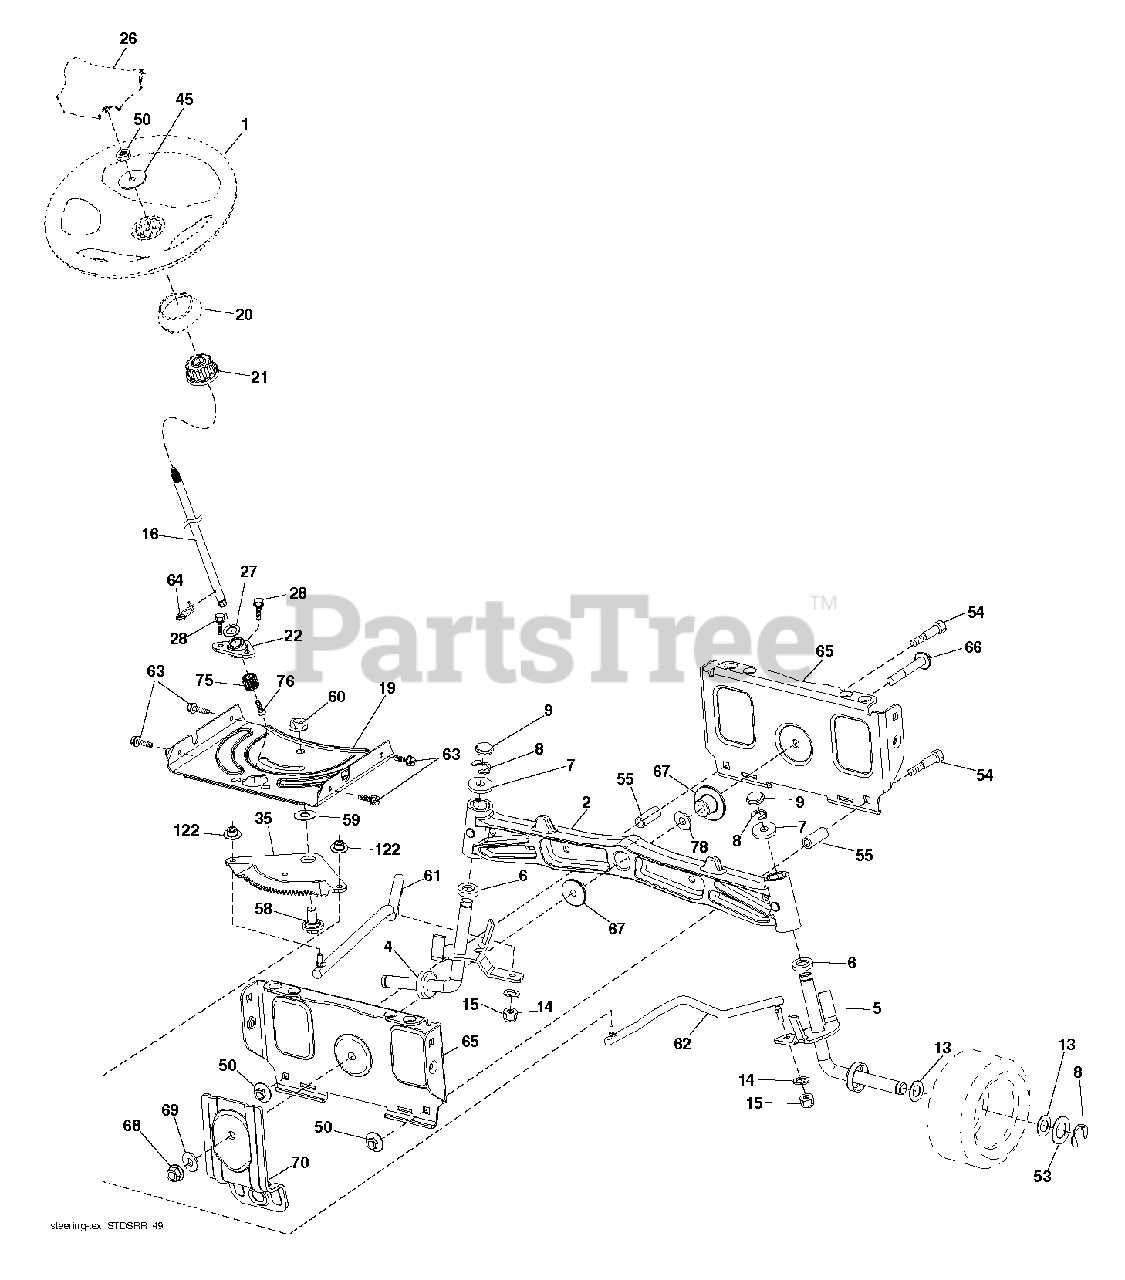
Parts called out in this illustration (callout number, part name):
1	WHEEL.STEERING.STDSRR.BLK/OV
2	AXLE.CAST.IRON
4	SPINDLE.WELDED.LH.16"TEX
5	SPINDLE.WELDED.RH.16"TEX
8	RING CLIP
9	CAP.SPINDLE
14	WASHER, LOCK 3/8
15	NUT CROWNLOCK 3/8-24
16	Steering Shaft Service Kit
19	PLATE.STEER.DDL.NLT/NG
21	Steering Shaft Adapter Kit
22	Steering Shaft Service Kit
26	CAP.WHL.STRNG.STDSRRD.SRS.BLK
27	WASHER LT
28	SCREW, 3/8-16X3/4
35	GEAR.SECTOR.PLATE.DDL.
45	WASHER.3/8ID.2-3/8OD.12GA.PLTD
50	NUT LOCK FLG 3/8-16 UNC
53	WASHER.HARDENED
55	SPACER.BRACE.AXLE
58	BOLT.SHOULDER.SECTOR.P
59	WASHER.THURST.SECTOR.S
60	NUT FLANGE LOCK 5/8-11
61	DRAGLINK.LH.BALLSTUD.D
62	DRAGLINK.RH.BALLSTUD.D
63	SCREW
64	RETAINER.CLIP.SPRING.S
65	BRACE.AXLE.FRONT.NLT/N
66	BOLT HEX FGHD 7/16-14 X 3 SERR
67	BUSHING.PM.FRONT AXLE
68	NUT.LOCK.FLANGE.7/16
69	WASHER.1.5X.505X.118
70	Deck Suspension Bracket, Front RR
75	Steering Shaft Pinion Kit
76	Screw Head Socket Lrvb
78	THRUST WASHER
